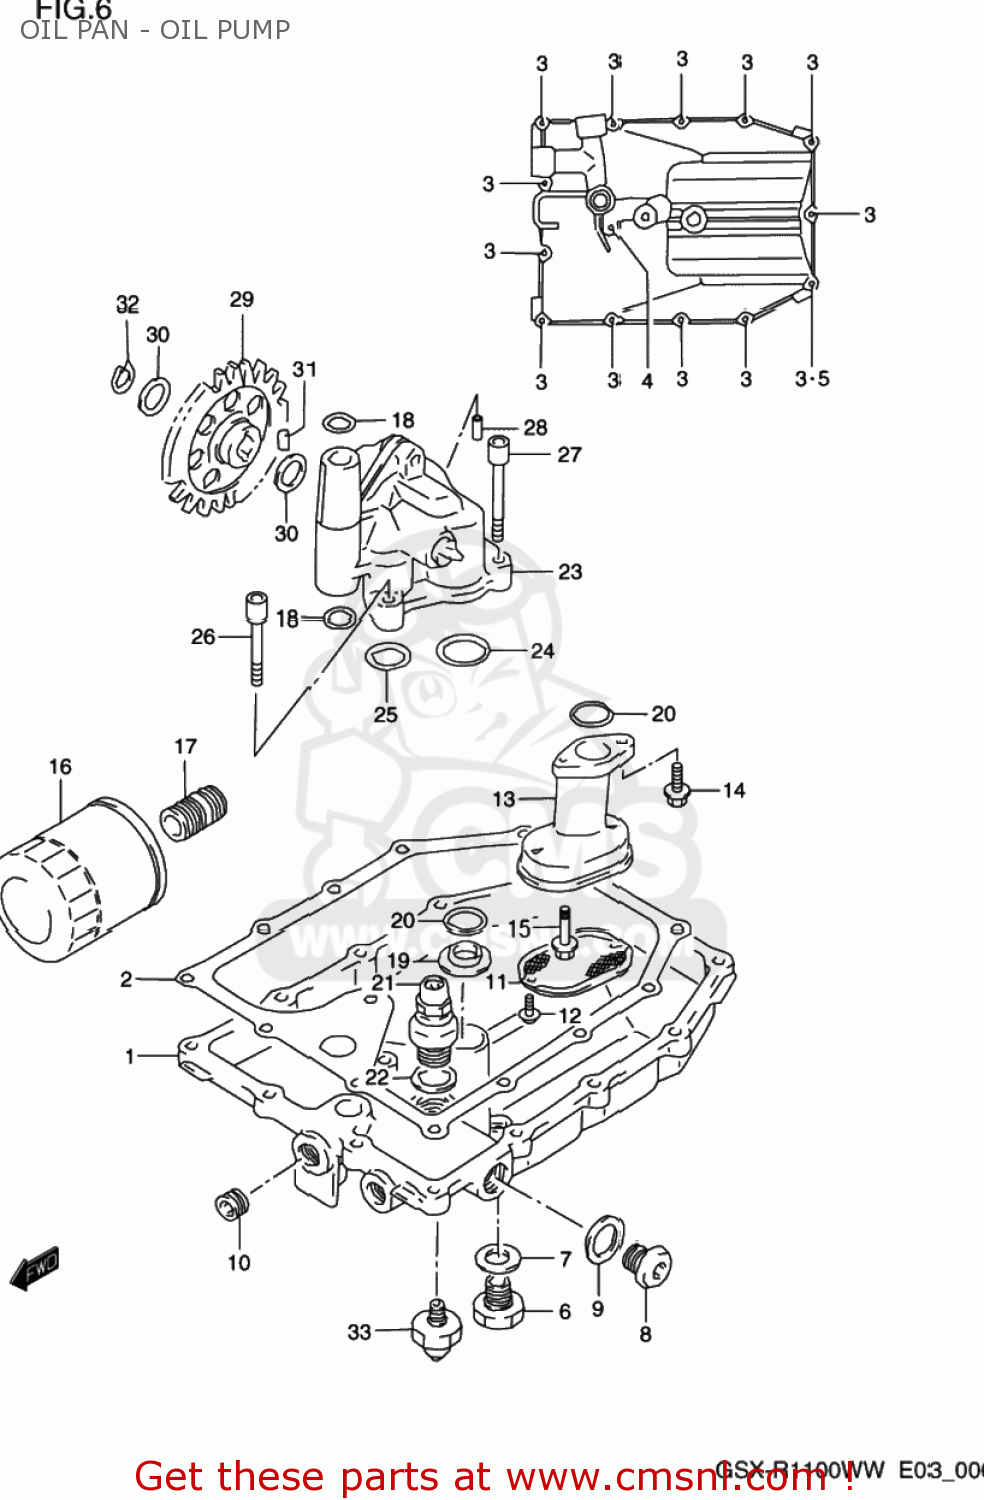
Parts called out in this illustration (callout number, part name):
1	PAN,OIL
2	GASKET,OIL PAN
3	BOLT
4	BOLT
5	GASKET(5.8X11X1.2) (NAS)
6	PLUG
7	GASKET(13.8X18.8X4.8) (NAS)
8	PLUG
9	GASKET(16X22X2) (NAS)
10	JET,OIL PAN GALLERY
11	STRAINER,ENGINE OIL
12	BOLT
13	PROTECTOR,OIL STRAINER
14	BOLT
15	BOLT
16	FILTER ASSEMBLY,ENGINE OIL
17	UNION,OIL STAND
18	O RING(D:2.4,ID:11.8)
19	GASKET,OIL OUTLET (NAS)
20	O RING(D:3.2,ID:17.8)
21	VALVE ASSEMBLY,OIL RELIEF
22	GASKET(16X22X2) (NAS)
23	PUMP ASSY,ENGINE OIL
24	O RING(D:2.4,ID:26.2)
25	O RING(D:3.2,ID:17.8)
26	BOLT
27	BOLT
28	PIN
29	GEAR,OIL PUMP DRIVEN(NT:37)
30	SHIM
31	PIN(5X18)
32	CIRCLIP,12 MM
33	SWITCH ASSEMBLY,OIL PRESSURE
